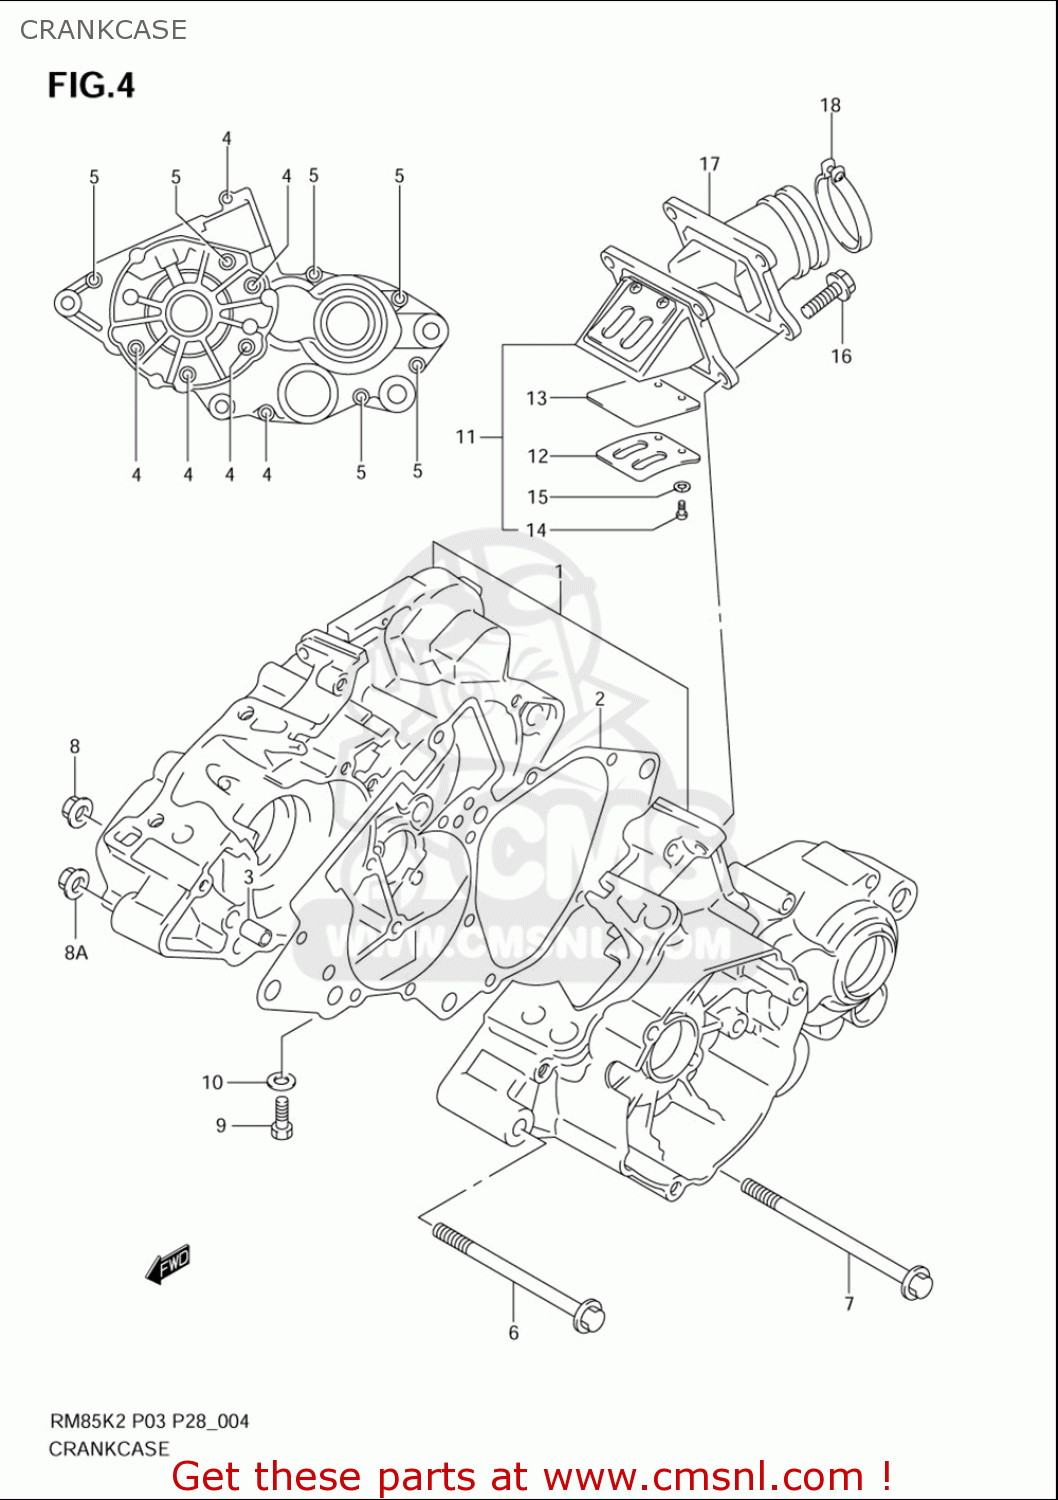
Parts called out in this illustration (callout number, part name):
1	CRANKCASE SET
2	GASKET,CRANKCASE (NAS)
3	PIN
4	BOLT(6X40)
5	BOLT(6X50)
6	BOLT(10X95)
7	BOLT(8X102)
8	NUT
8A	NUT
9	BOLT
10	GASKET(8.2X14X1) (NAS)
11	VALVE ASSY,REED
12	STOPPER,REED VALVE
13	VALVE,REED
14	SCREW
15	WASHER,LOCK
16	BOLT,6X20
17	PIPE,INTAKE
18	CLAMP
